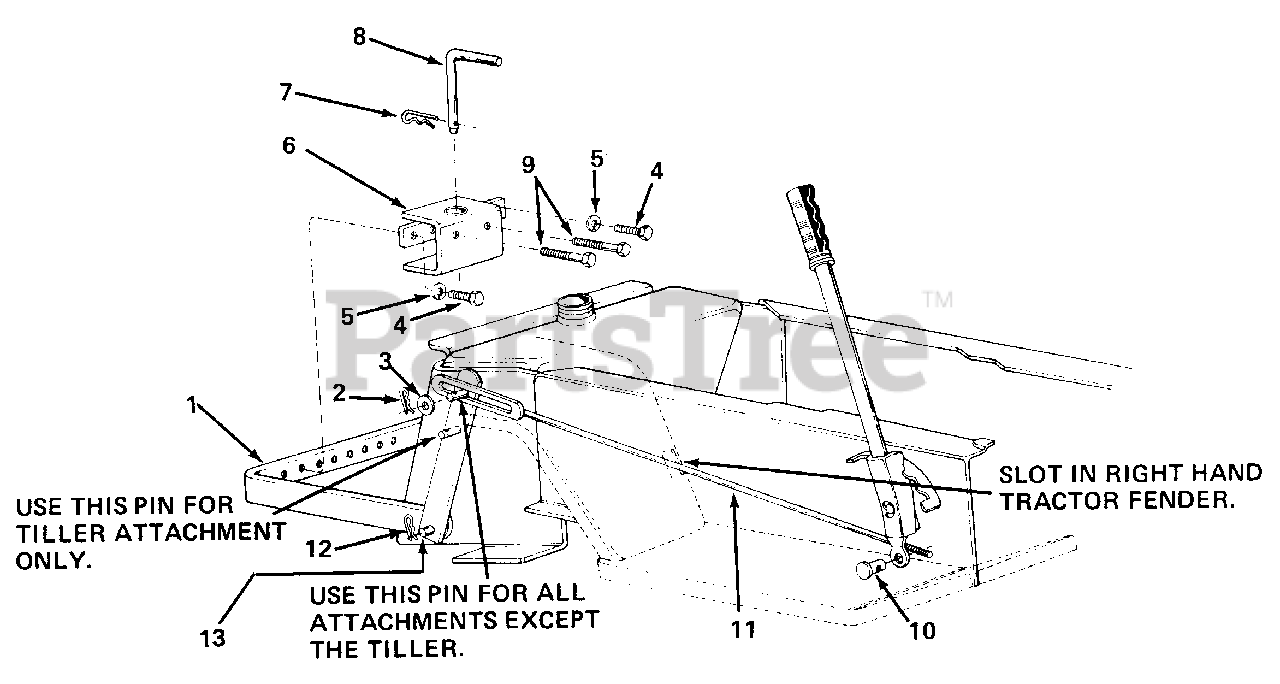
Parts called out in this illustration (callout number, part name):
3	Fl.-Wash. 1/2" I.D.
4	Hex Scr. 1/2-13 x 1.00" Lg.
5	L.-Wash. 1/2" Scr.
8	Hitch Pin
9	Hex Scr. 1/2-13 x 3.00" Lg.
10	Adjustment Ferrule
13	Hitch Rod
